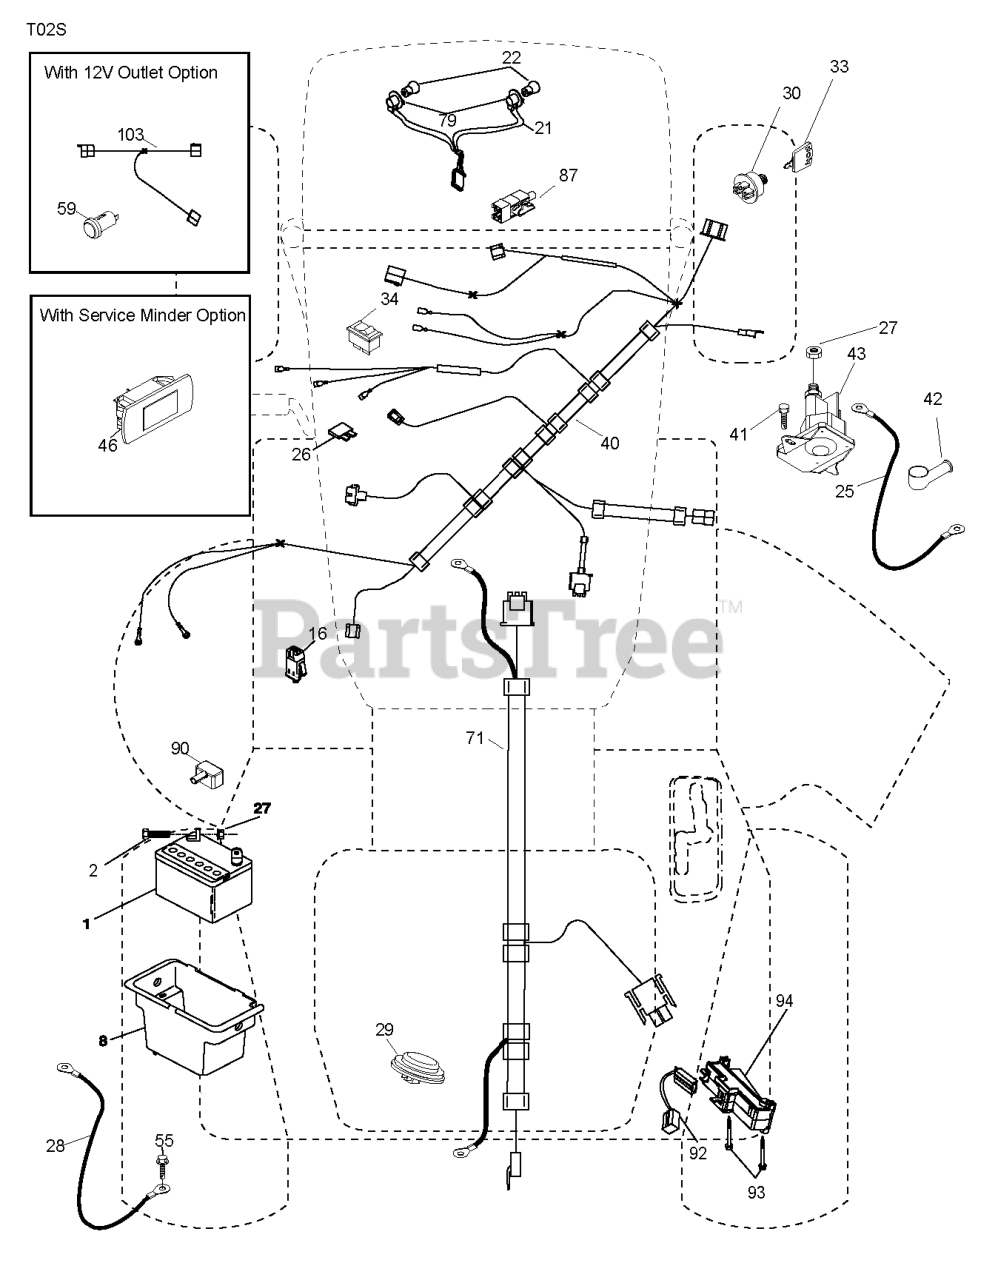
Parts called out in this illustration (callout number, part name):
1	Battery 12 Volt 25 Amp
2	BOLT.HEX.1/4.X.3/4.DICHROMATE
8	BOX.BATTERY.MNT.REAR.L
16	SWITCH INTERLOOK PUSH-IN
21	HARNESS.LIGHT W/4152J BULBS
25	CABLE.STARTER.6GA.BL/RED.14.
26	FUSE 20AMP
27	NUT
28	CABLE.BLACK.18"REAR.BA
29	SWITCH.SEAT.DELTA.OPC.
30	SWITCH.IGN.DELTA.W.LGH.ROS
33	KEY.CHAIN.BLISTER.PACK.GEN.INT
40	HARNESS IGN. DASH
41	SCREW
42	TERMINAL COVER
43	SOLENOID.W/BRASS.PLUNGER
46	RP.GUAGE.SRVCMNDR.HRMTR.
55	SCREW 5/16"
71	HARNESS.IGN.CHASS.TEX.REAR.BAT
79	BULB HOLDER ASM.
87	SWITCH.INTRLCK.CLUTCH.
90	COVER, TERMINAL BATTERY
92	HARNESS.PIGTAIL.CONSLE
93	SCREW.PLASTITE
94	MODULE.REVERSE.ROS
